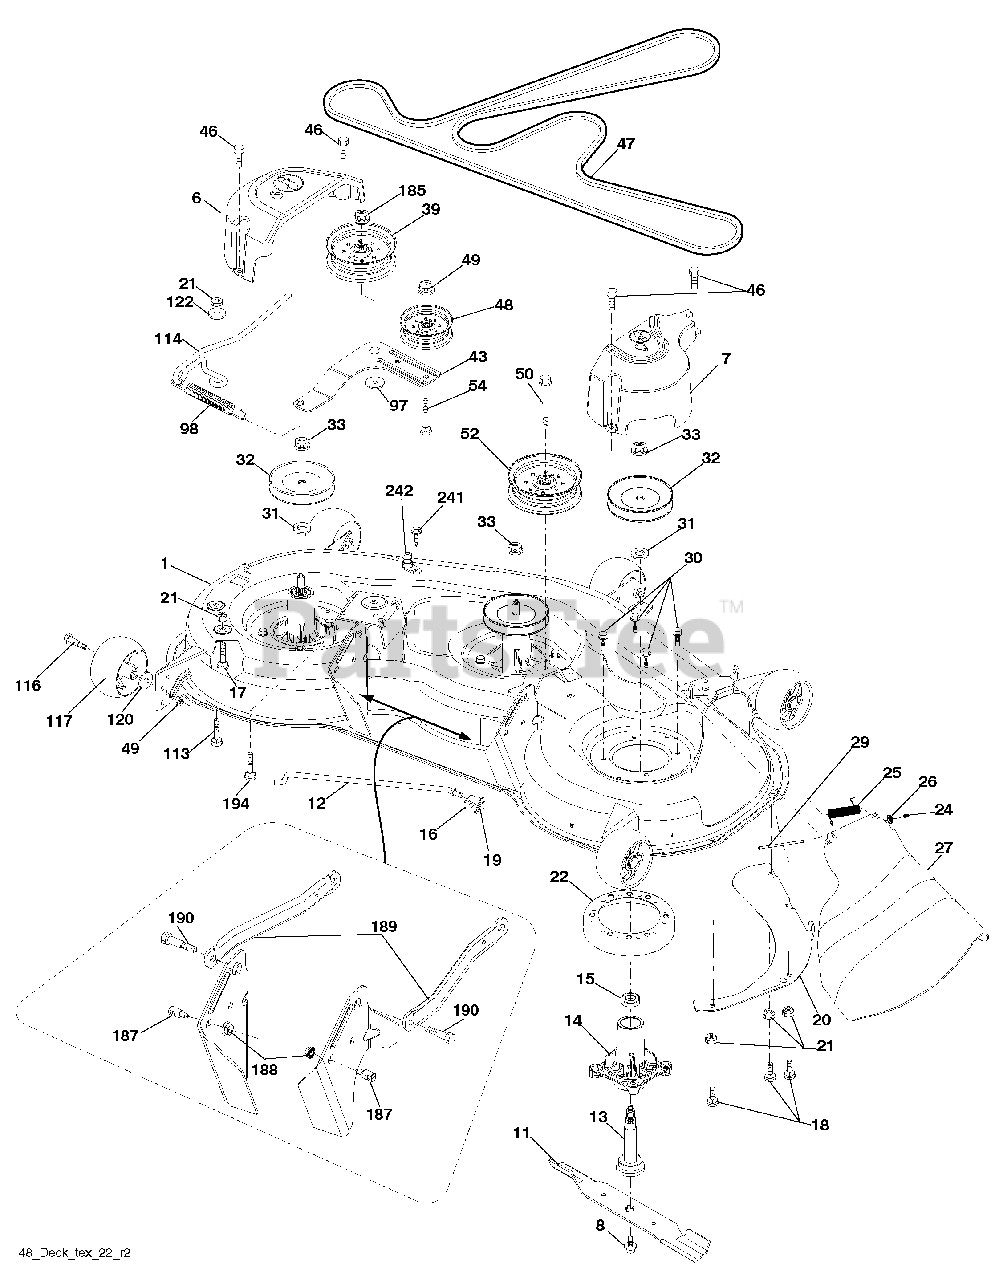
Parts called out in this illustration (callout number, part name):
1	Deck Weldment Mower
2	Plug Hole Mandrel
6	Cover Mandrel LH
7	Cover Mandrel RH
8	Blot/Washer Asm 7/16-20 unf
11	Blade High Lift
11	Blade Mulching
12	Rod Anti-Sway
13	Shaft Asm. Mandrel
14	Housing, Mandrel
15	Bearing, Ball, Mandrel
16	Washer 13/32 x 13/16 x 12 Ga.
17	Bolt 5/16-18 x 5/8
18	Bolt RdHd 5/16-18 unc x 5/8
19	Pin Cotter 5/16 Bow Tie Lock
20	Baffle Vortex
21	Nut, Crownlock 5/16-18 unc
22	Stripper Mandrel
24	Cap Sleeve
25	Spring, Torsion
26	Nut, Push
27	Deflector Shield
29	Rod, Hinge
30	Screw, Thdroll Washer Head
31	Spacer Mandrel
32	Pulley, Mandrel
33	Nut, Flg. Top Lock
39	Pulley, Idler
43	Arm, Idler
46	Screw, Thdroll. 1/4-20 x 5/8
47	Belt Deck Drive
48	Pulley Idler
49	Nut, Lock Flg. 3/8-16 unc
50	Screw TT 3/8-16 x 2-1/4
52	Pulley Idler Clutching
54	Bolt Carr. Sh 3/8-16 x 1-1/2 Gr. 5
97	Washer Hardened
98	Spring Drive
113	Bolt Rdhd Sqnk 5/16-18 x 3/4
114	Rod Tension Relief
116	Bolt, Shoulder
117	Gauge Wheel
120	Washer 13/32 x 1-1/4 x 12 Ga.
122	Bushing Tension Relief
185	Nut Lock Flange 7/16-14 Gr. 5
187	Stud Fastener w/"D" Anti-Rotation
188	Nut Lock Hex Flange
189	Arm Susp. Mower Rear
190	Bolt Shoulder
194	Bolt Carr Sqnk 7/16-24 x 2
241	Screw
242	Port Washout
242	Cooupling Quick Connect
242	Mandrel Assembly
242	Replacement Mower, Complete
